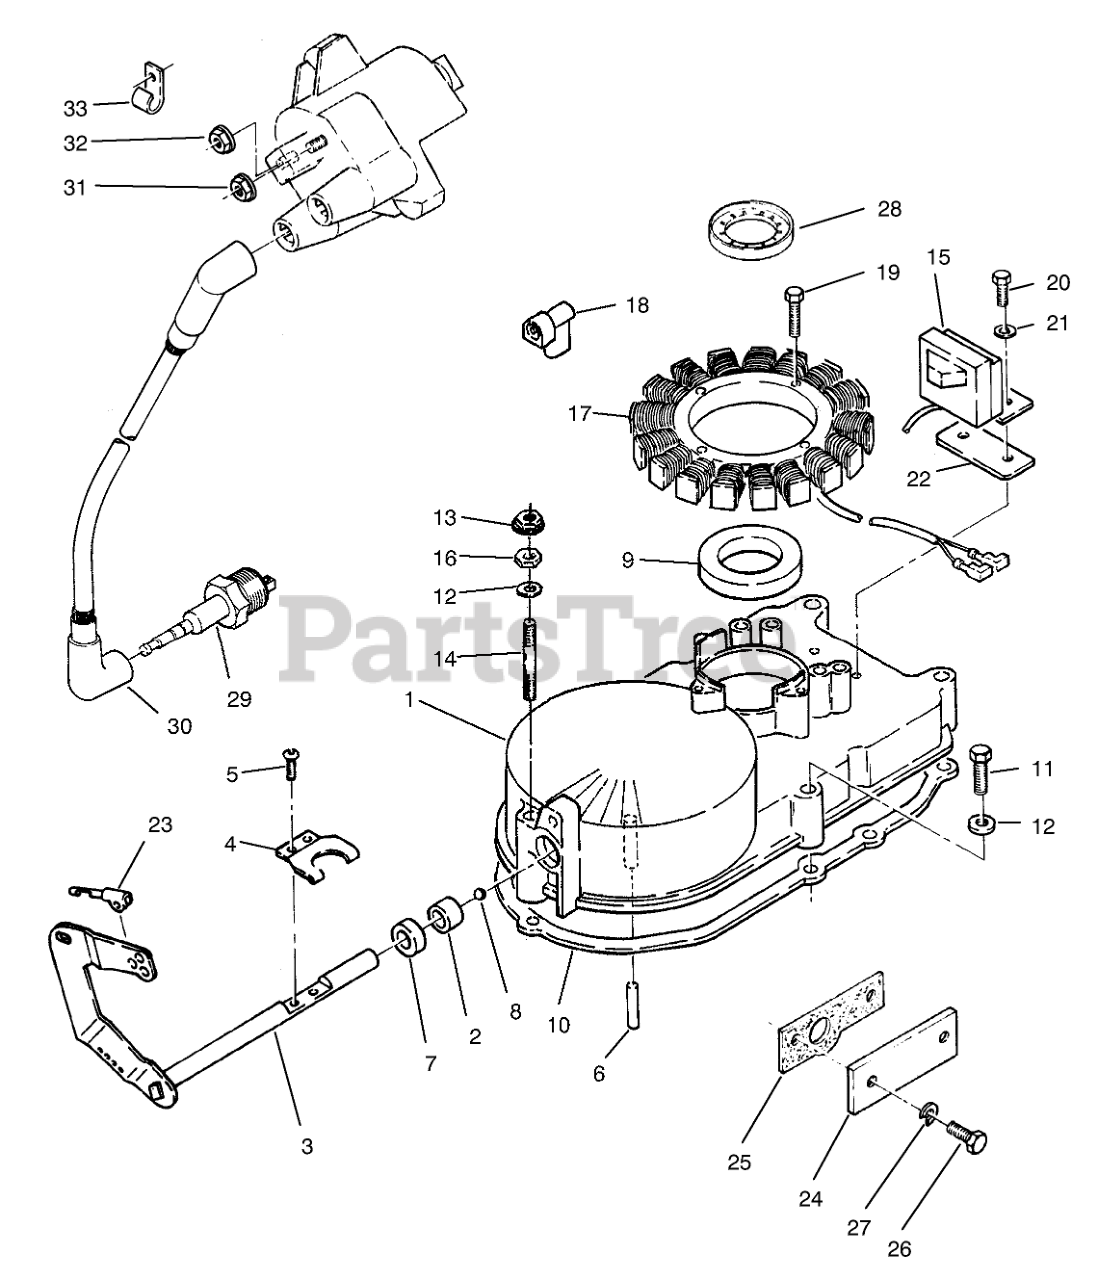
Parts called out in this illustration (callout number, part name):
1	GEAR-CASE KIT
5	SCREW-PAN HD
12	WASHER
16	NUT-GEAR COVER
25	GASKET
29	SPARK PLUG
